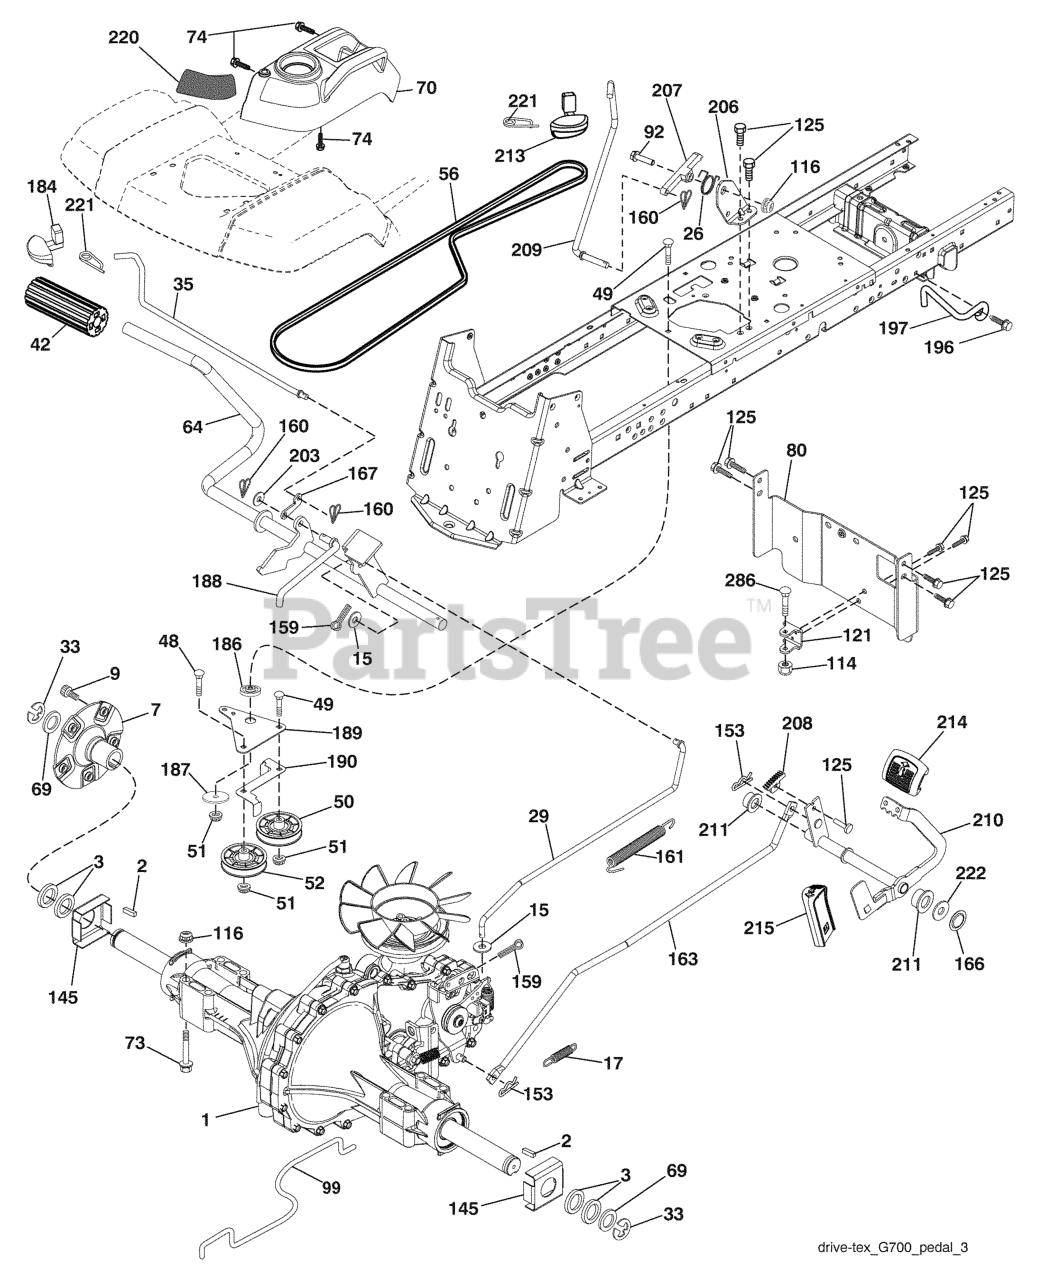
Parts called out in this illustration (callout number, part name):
2	KEY 1/4 X 2.5
7	HUB.ASM.WHEEL.REAR.23"TEX
9	HUB BOLT
15	WASHER
17	SPRING.BRAKE.HG3000/3500
26	SPRING.RETURN.CRUISE
33	E RING HYT
35	ROD.BRAKE.PARKING.GT.H
42	PEDAL COVER T
48	BOLT.3/8-16X1.50
50	IDLER.FLAT.910.OFFSET
51	NUT LOCK FLG 3/8-16 UNC
52	IDLER.V-GROOVE.910.OFFSET
56	V-BELT.GROUND.DRIVE.
64	SHAFT.ASM.PEDAL.BRK.CNTR
70	RP CONSOLE.ASM.PCH.W/TB
73	BOLT HEX FLGHD 5/16-18X3 GR. 5
74	SCREW.HI-LO.CONSOLE
80	STRAP.TORQUE.YT.G700
92	BOLT
99	SPRING.BYPASS.YT.G700
114	NUT.71038.31-18.HEX.NYLOCK
116	NUT LOCK HEX FLANGE 5/16-18
121	BRACKET STRAP TORQUE
125	SCREW
145	WASHER.AXLE.FLANGE.HG-3000
153	RETAINER M
159	COTTER PIN
160	RETAINER CLIP
161	SPRING, RETURN LT
163	ROD PEDAL CONTROL
166	NUT.PUSH.625.2006
167	LATCH.BRAKE.SPRING
184	HANDLE.PARKG.BRK.HUSQ X667
186	SPACER.RETAINER
187	WASHER 12/32X2X10GA
188	RP.LINK.CLUTCH.GROUND.DRIVE
189	BELLCRANK.GROUND.DRIVE.TRAPPED
190	KEEPER BELLCRANK ROUND DRIVE
196	SCREW 3/8-16X1
197	BRKT.ANIT-ROTATION.CLUTCH
203	WASHER
206	BRKT.MOUNT.LATCH.CRUIS
207	LATCH.CONTROL.CRUISE
208	GEAR.SECTOR.CONTROL.CR
209	ROD.CONTROL.CRUISE.GT.
210	ROCKER.ASM.PEDAL.CONTR
211	BEARING.NYLON
213	KNOB.CONTROL.CRUSIE.HU
214	PEDAL.FORWARD.HUSQVARNA.DEALER
215	PEDAL.REVERSE.TEX.GT.4
220	REFLECTOR.LH.TEX GT HU
221	RETAINER.SPRING.CLIP.H
222	WASHER 21/32 X 1-1/4 X 10 GA.
286	Bolt 5/16-18 x 2.75
